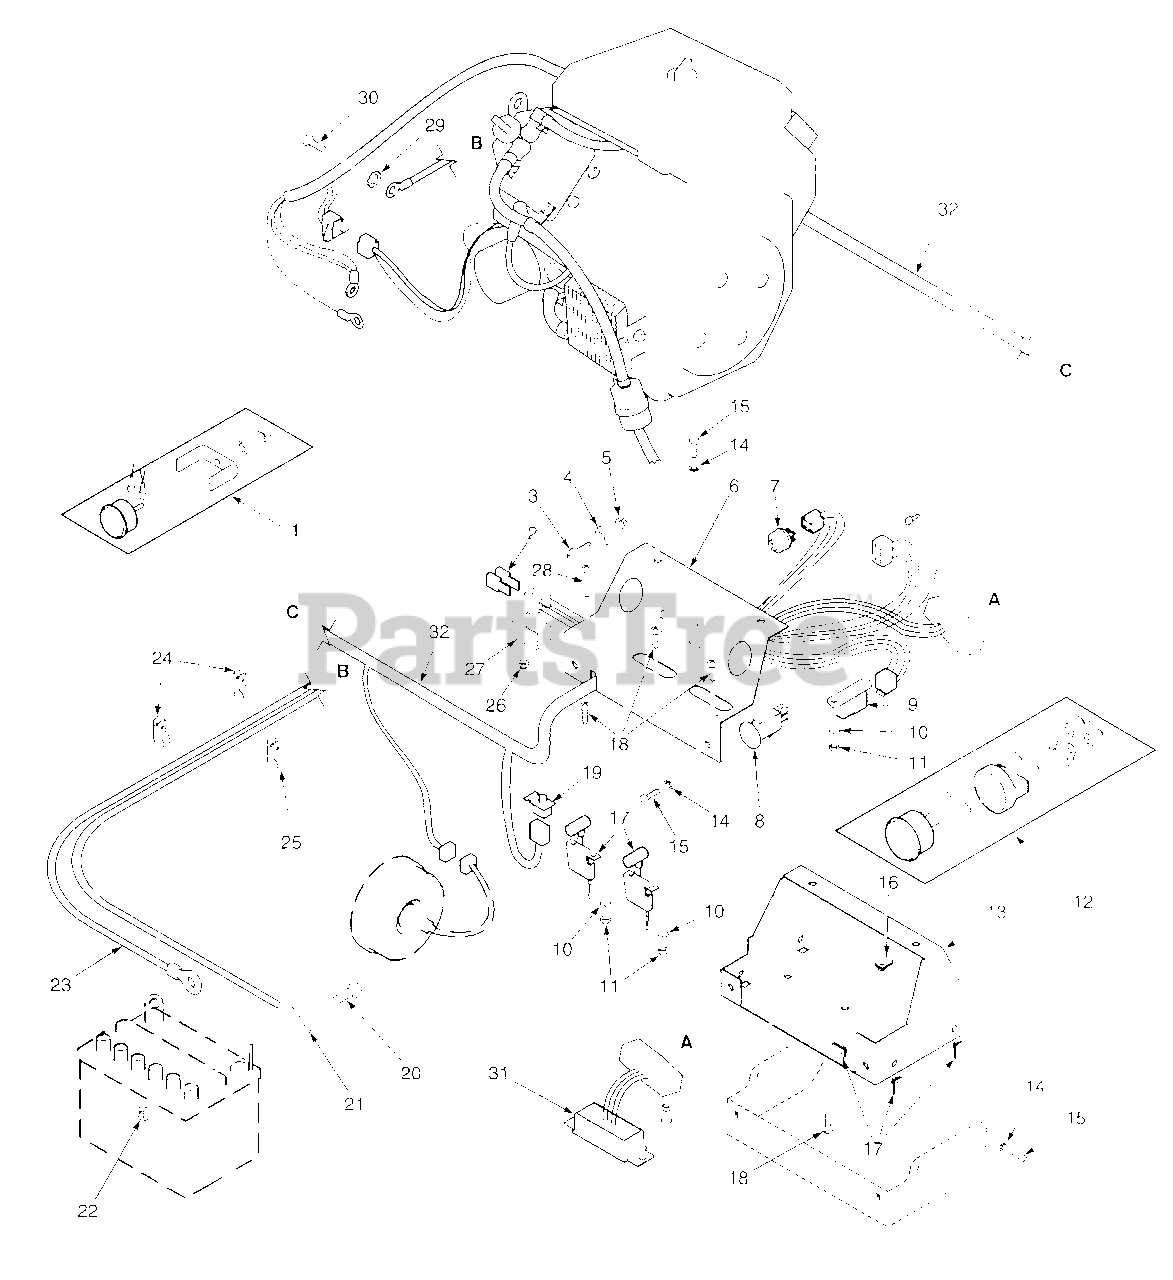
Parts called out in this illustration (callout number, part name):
1	Hour Meter
2	Fuse, 20 AMP
3	Key & Ring Assembly
4	Nut, Hex 5/8-32
5	Lockwasher, 5/8" Internal
6	Instrument Panel, Top
7	Key Switch
8	Switch, PTO
9	Relay
10	Lockwasher, #10 External Tooth
11	Nut, Hex #10-32
12	Ammeter
13	Base, Instrument Panel
14	Lockwasher, 1/4"
15	Bolt, Hex Head 1/4-20 x 3/4"
16	U-Nut, 1/4-20
17	Throttle And Choke Controls
18	Screw, Phillips Washer Head #10-32 x 1/2"
19	Switch, Interlock-Seat
20	Bolt, Hex Head 1/4-20 x 1/2"
21	Cable, Battery - Red 20"
22	Nut, Hex 1/4-20
23	Cable, Battery - Black
24	Clamp, Cable 1/2" ID.
25	Clamp, Cable 3/4" ID.
26	Nut, Hex Elastic Stop #10-32
27	Bracket, Fuse Holder
28	Screw, Phillips Washer Head #10-32 x 1-1/2"
29	Lockwasher, 5/16" External Tooth
30	Bolt, Hex Head M8-1.25 x 20
31	Electronic Module
32	Wire Harness, STT
